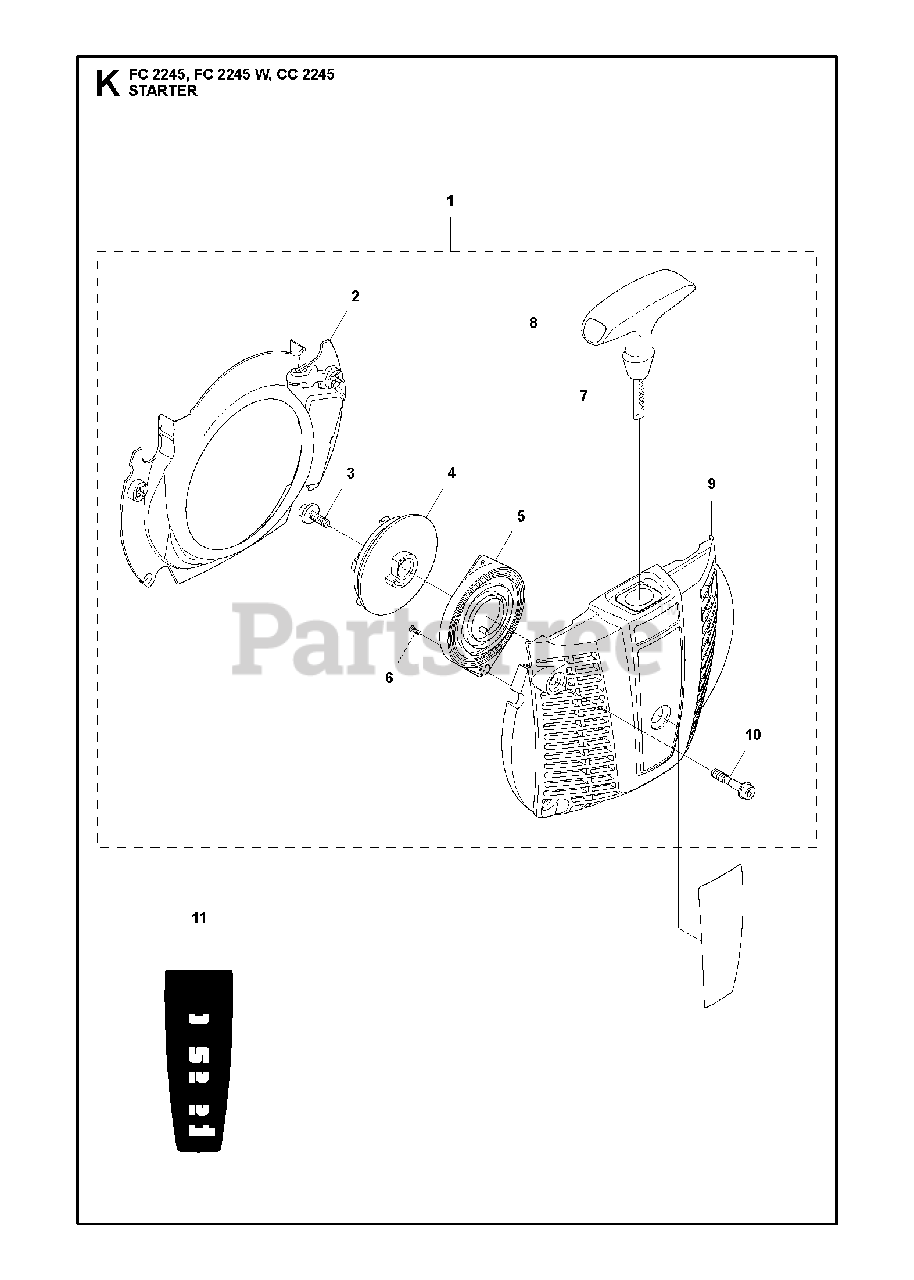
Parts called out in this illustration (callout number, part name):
2	COOLING AIR CONDUCTOR
3	SCREW
4	STARTER PULLEY
5	RECOIL SPRING
6	SCREW
7	STARTER ROPE
8	STARTER HANDLE
9	STARTER HOUSING
10	SCREW IHSCFMO
